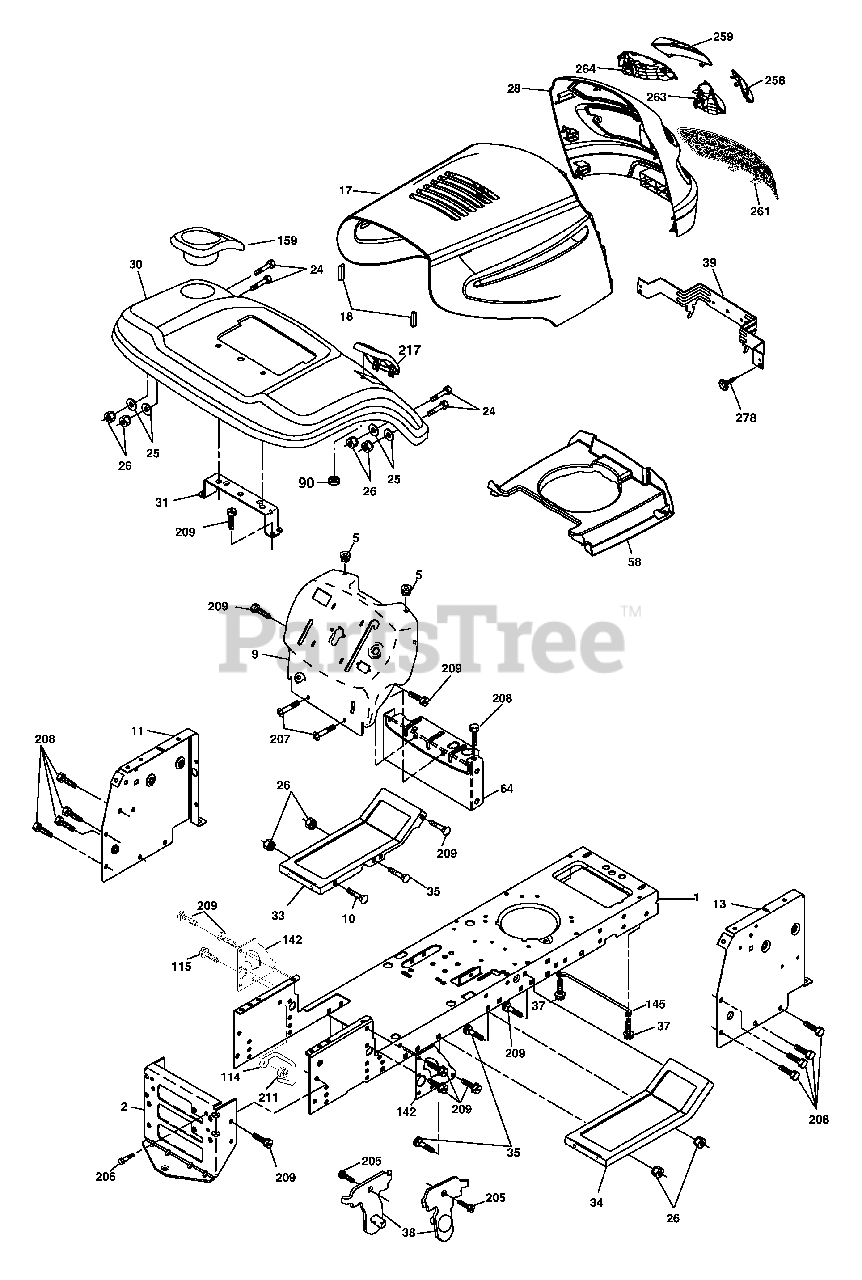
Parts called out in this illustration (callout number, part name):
1	Chassis
2	Drawbar
5	Bumper Hood/Dash
9	Dash P/L
10	Bolt Carriage 3/8-16 x 1
11	Panel Dash Lh
17	Hood
18	Bumper Hood
24	Bolt Fin Hex 3/8-16 unc x 1 Gr. 5
25	Washer 13/32 x 13/16 x 12 Ga.
26	Nut Lock Hex W/Ins 3/8-16 unc
28	Grille/Lens Asm
30	Fender
31	Bracket Fender
33	Footrest LH
34	Footrest RH
35	Bolt RDHD SHT SQNK 3/8-16 x 3/4
37	Screw Thdrol 6/16-18 x 1/2 TYT
38	Bracket Asm Pivot Mower Rear
39	Bracket Pivot
58	Duct Air
64	Dash Lower STLT
90	Nut Self-Thd Wsh-Hd
114	Keeper Belt Rear LH
115	Screw THDROL 3/8-16 x 1-1/4
142	Plate Reinforcement STLT
145	Rod Pivot Chassis/Hood
159	Cupholder
206	Bolt Shoulder 5/16-18
207	Screw Thdrol 5/16-18 x 1/2
208	Screw Thdrol 3/8-16 x 1/2
209	Screw Hexwsh Thdr 3/8-16 x 3/4
211	Nut Hex Flange Lock
217	Console Fuel Window
258	Lens Grille Pro RH
259	Lens Grille Pro LH
263	Bezel Grille RH
264	Bezel Grille LH
278	Screw 10 x 3/4 Single Lead
